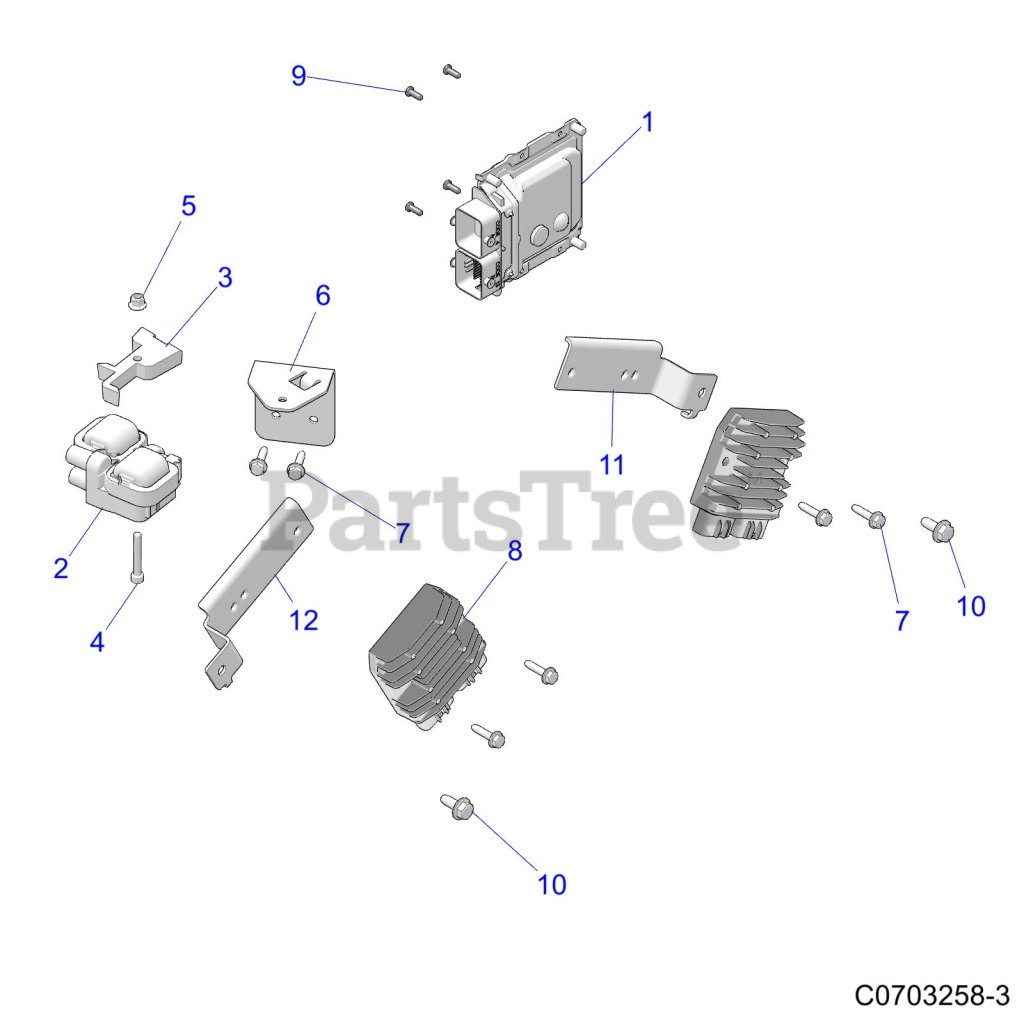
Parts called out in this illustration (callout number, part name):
1	ECM-NO START,ME17
2	COIL-EFI
3	SPACER-COIL MOUNT
4	SCR-M6X1.0X40,HX/SOC/CP-B
5	NUT-M6 FLANGE,NYLOK
6	BRKT-COIL,MOUNT
7	SCR-TFHFL-M6X1.0X25,ZTC
8	REGULATOR-3PH,35A,SERIES,105C
9	SCR-#10X1/2-HI/LO-PN-T25,TRX-M
10	BOLT-M8X1.25X20,HXFLG,TAP/R-OD
11	BRKT-MOUNT,REG
12	BRKT-MOUNT,REG
